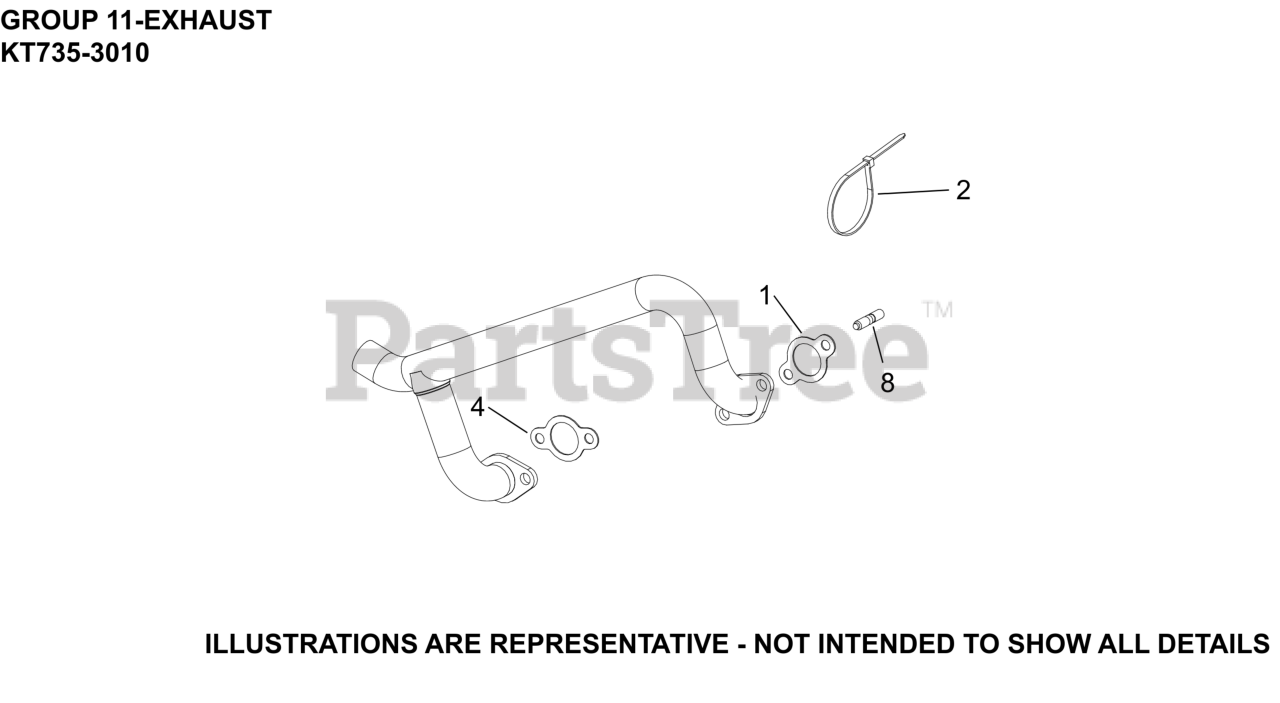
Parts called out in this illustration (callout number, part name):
1	GASKET, EXHAUST MANIFOLD
4	NUT, HEX FLANGE LOCK (M8)
8	STUD, METRIC EXHAUST
